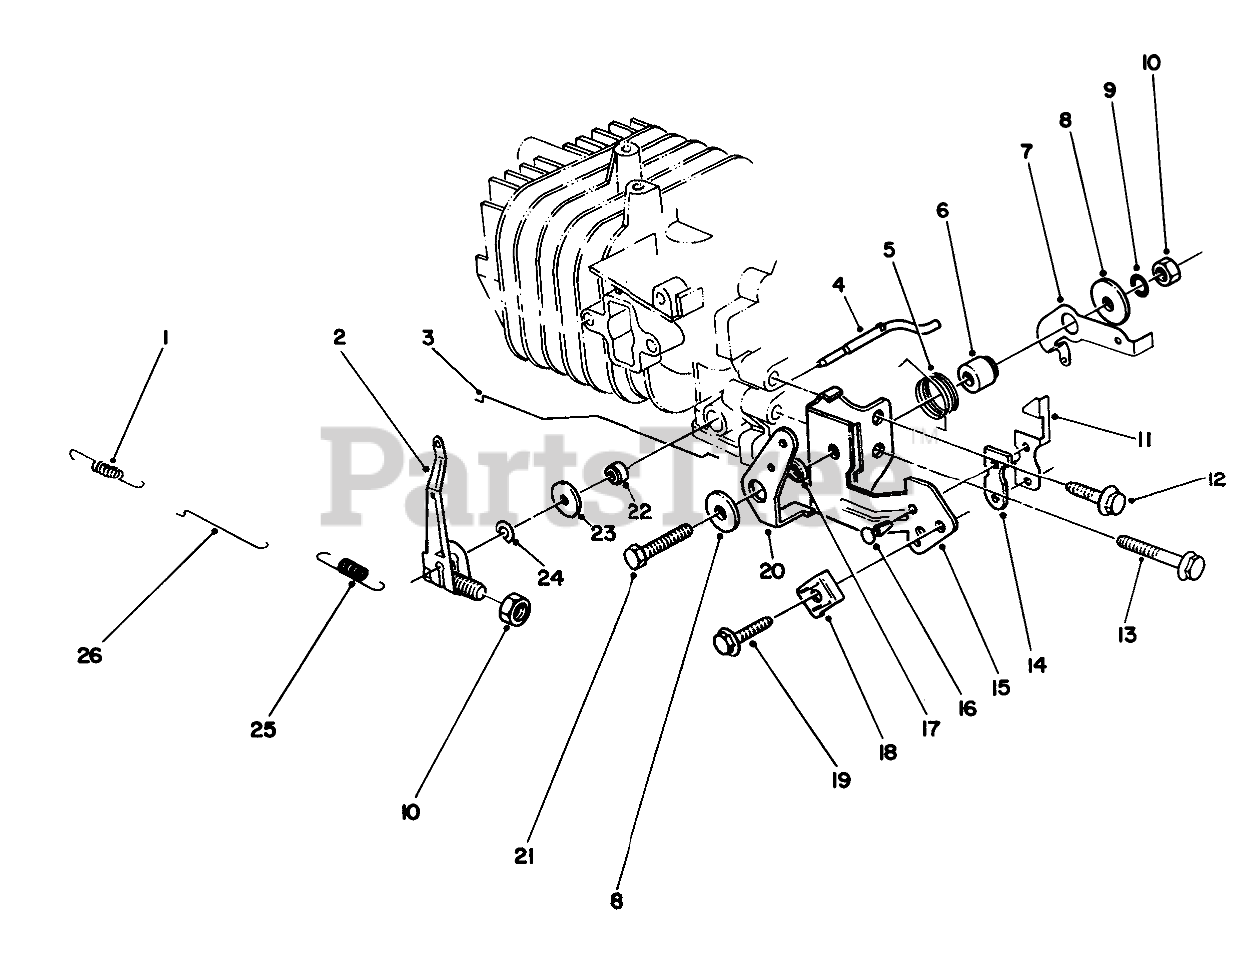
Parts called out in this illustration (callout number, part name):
1	SPRING
2	GOVERNOR ARM
3	CHOKE ROD
4	Shaft-Govemor
5	SPRING-CHOKE LEVER
6	Gov Lever Spacer
7	LEVER-SPRING, GOVERNOR
8	WASHER
9	LOCKWASHER
11	TERMINAL-KILL SWITCH
14	INSULATOR-KILL SWITCH
15	BRACKET-THROTTLE, CONTROL
16	KILL SWITCH RIVET
17	SPACER-CHOKE LEVER
18	CLAMP
20	LEVER-CONTROL, CHOKE
22	SEAL-OIL
23	WASHER
24	E-RING
25	SPRING-GOVERNOR
26	ROD-CARBURETOR
